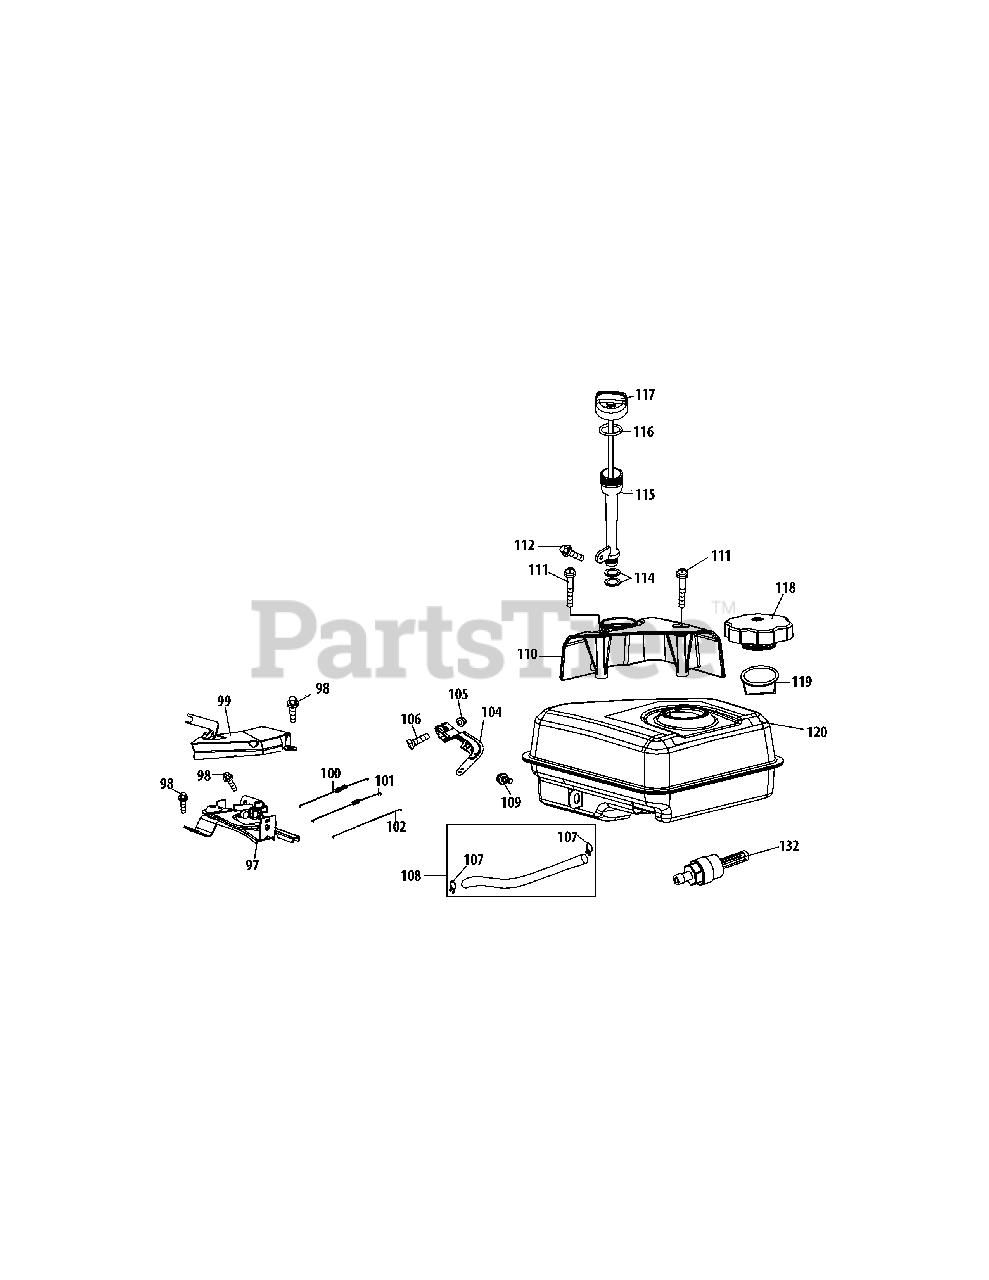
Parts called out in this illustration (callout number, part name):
97	Throttle Control Assemlby
98	Bolt M6×12
99	Governor Shield
100	Governor Spring
101	Throttle Linkage Spring
102	Throttle Linkage
104	Governor Arm
105	Nut M6
106	Governor Arm Bolt
107	Fuel Hose Clamp
108	Fuel Line Kit
109	Bolt M6×12
110	Engine / Dipstick Cover
112	Bolt M6×12
114	Oil Fill Tube O-Ring
115	Oil Fill Tube
116	Dipstick O-Ring
117	Dipstick Guage
118	Fuel Cap Assembly
119	Fuel Level Indicator
120	Fuel Tank Assembly
132	Fuel Tank Nipple
